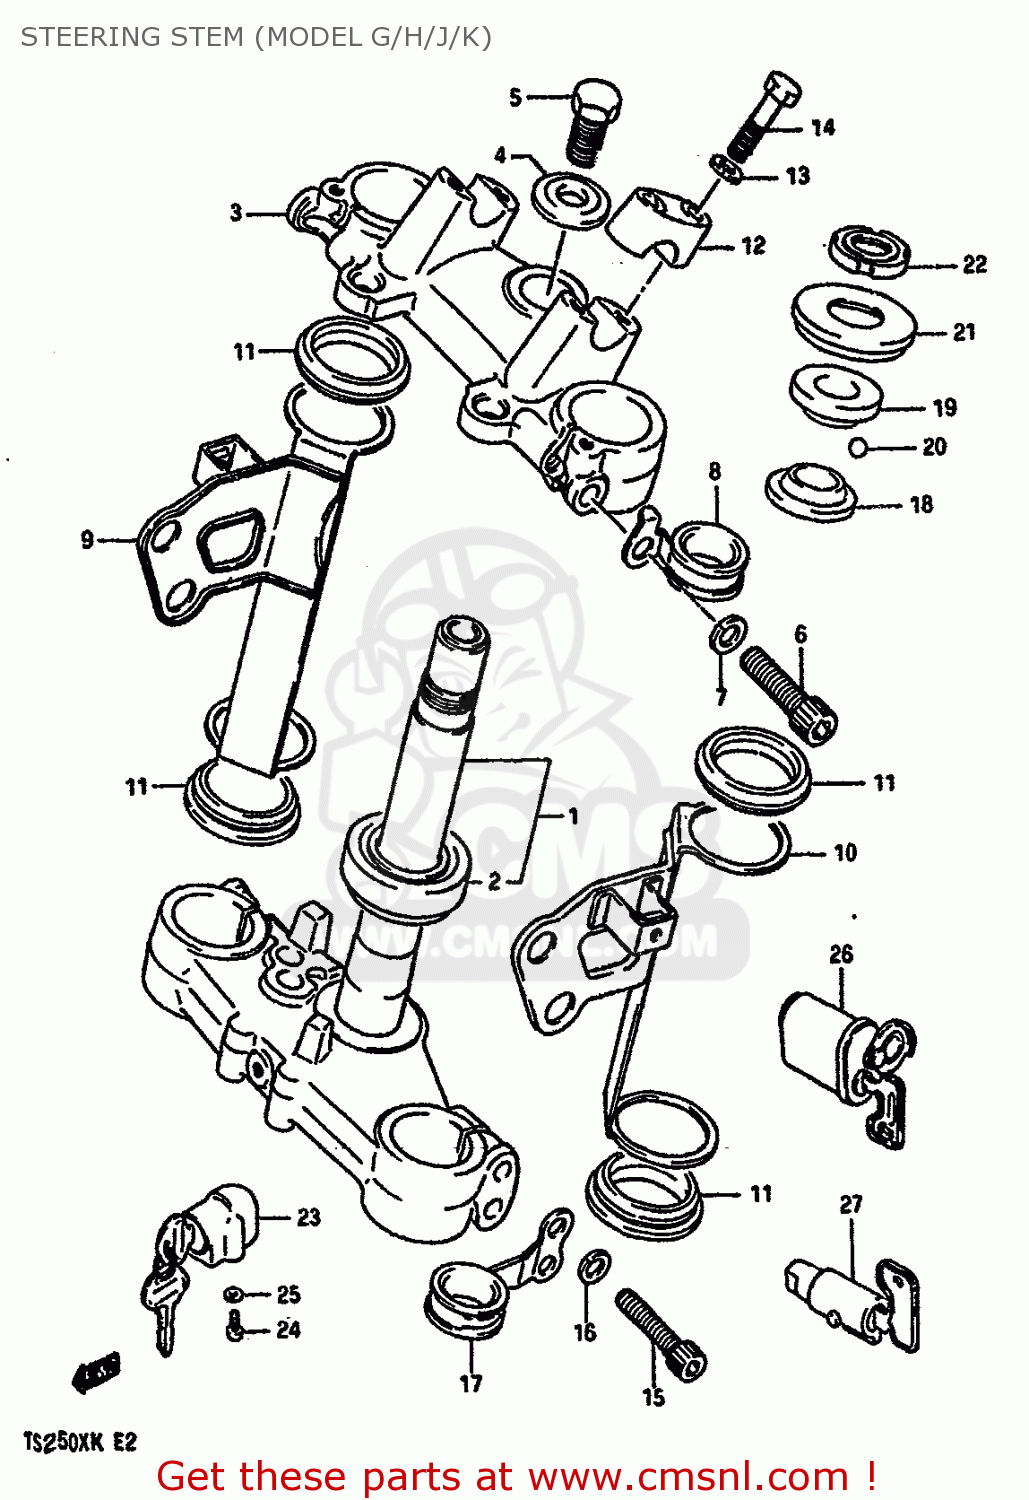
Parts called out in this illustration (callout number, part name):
1	STEM,STEERING
2	BEARING
3	HEAD,STEERING STEM
4	WASHER
5	BOLT
6	BOLT,REAR LH
7	LOCK WASHER
8	CLIP
9	BRACKET,HEADLAMP RH
10	BRACKET,HEADLAMP LH
11	GASKET
12	HOLDER,HANDLEBAR
13	LOCK WASHER
14	BOLT
15	BOLT, RH
16	WASHER,LOCK
17	CLIP
18	RACE,STEERING INNER (SUJ)
19	RACE,STEERING,OUTER,UPPER
20	BALL
21	SEAL,STEERING UPR DUST
22	NUT,STEERING STEM
23	LOCK ASSY,STEERING
24	SCREW
25	LOCK WASHER
26	LOCK ASSY, STEERING (NEIMAN TYPE EXECUTE
27	LOCK ASSY,STEERING(NEIMAN)
